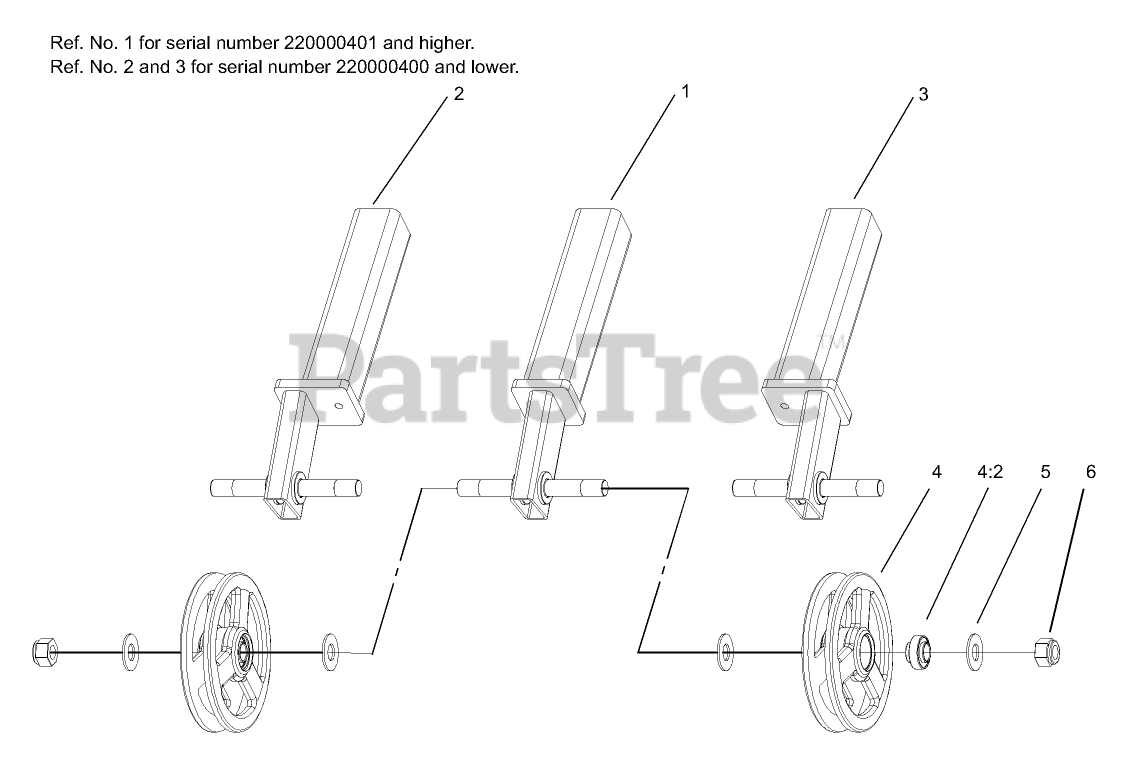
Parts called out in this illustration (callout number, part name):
2	RH TENSIONER ARM ASM
3	LH TENSIONER ARM ASM
4	TENSIONER WHEEL ASM
4:2	BEARING-BALL
5	WASHER-FLAT
6	NUT-HEX, NI
